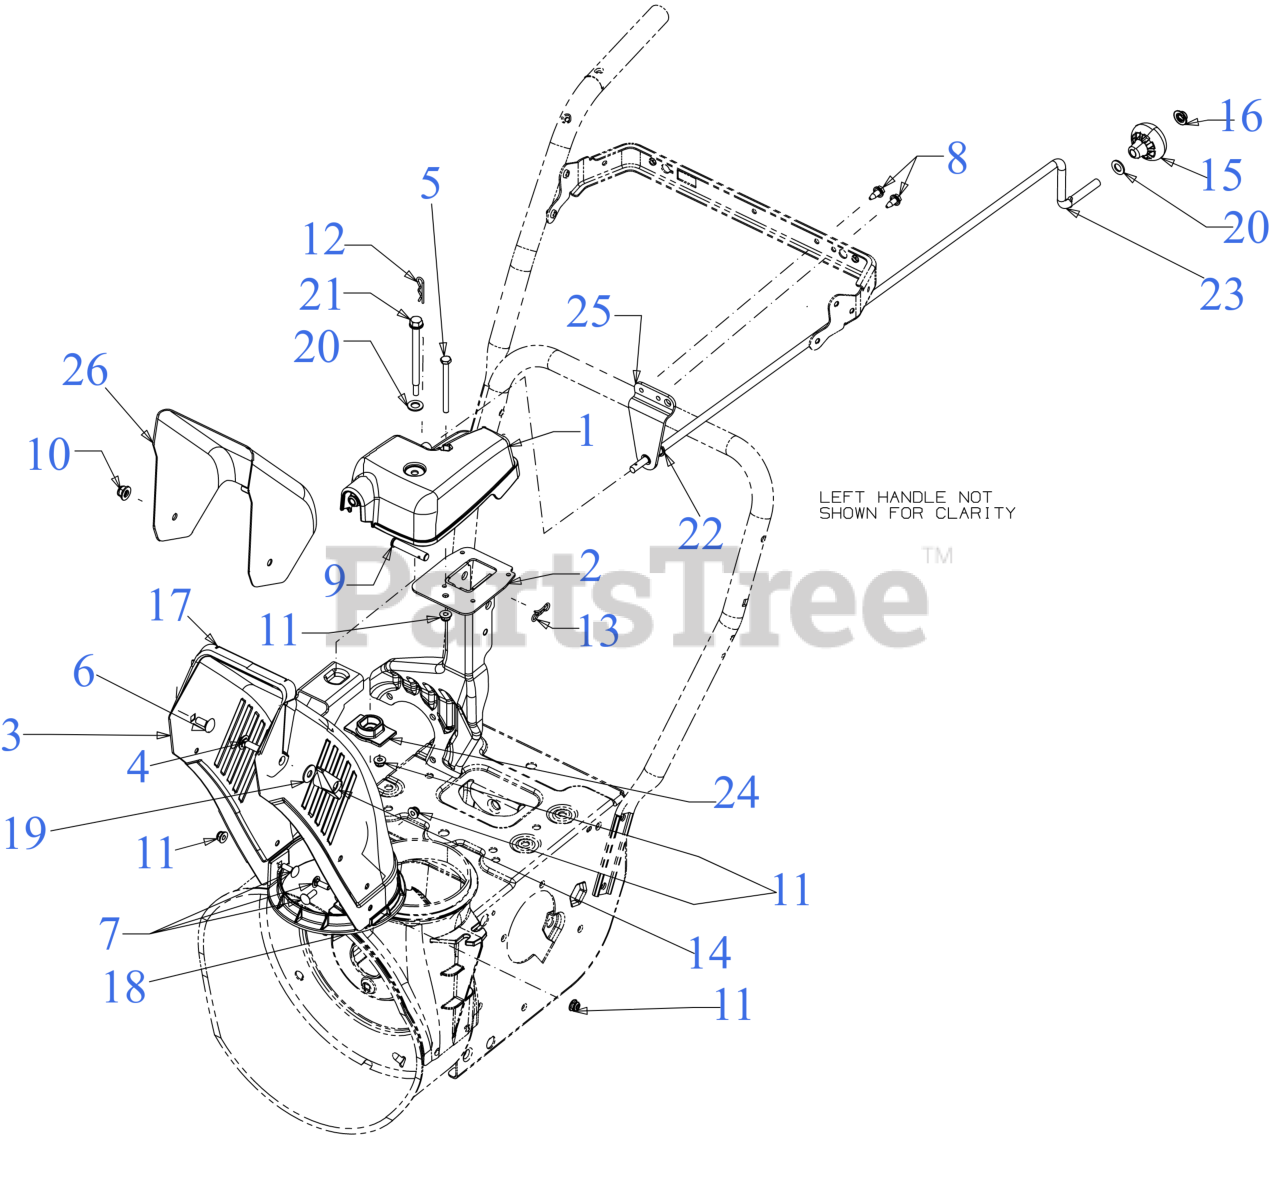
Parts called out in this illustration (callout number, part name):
1	2-WAY CHUTE ROTATE GEARBOX
2	CHUTE SUPPORT ASSEMBLY
3	STEEL CHUTE
4	CARRIAGE BOLT 5/16-18 x 1.00
5	SCREW 1/4-20 x 3.0 GR5
6	CARRIAGE BOLT 5/16-18 x .75
7	SCREW 1/4-20 x .75 GR5
8	SCREW 1/4-20X.625
9	CLEVIS PIN 3/8 x 1.87
10	FLANGE LOCK NUT 5/16-18
11	FLANGE LOCK NUT
12	INTERNAL COTTER PIN
13	BOW TIE COTTER PIN 1/4-5/16
14	WING KNOB NUT
15	SHIFT KNOB
16	PUSH NUT
17	UPPER CHUTE ADAPTER
18	CHUTE BASE 5.0 DIA
19	FLAT WASHER
20	FLAT WASHER
21	SHOULDER SCREW
22	BUSHING .380 ID
23	CHUTE CRANK .375 DIA x 31"
24	HELICAL GEAR CHUTE ADAPTER
25	ROD SUPPORT BRACKET
26	STEEL CHUTE (UPPER)
